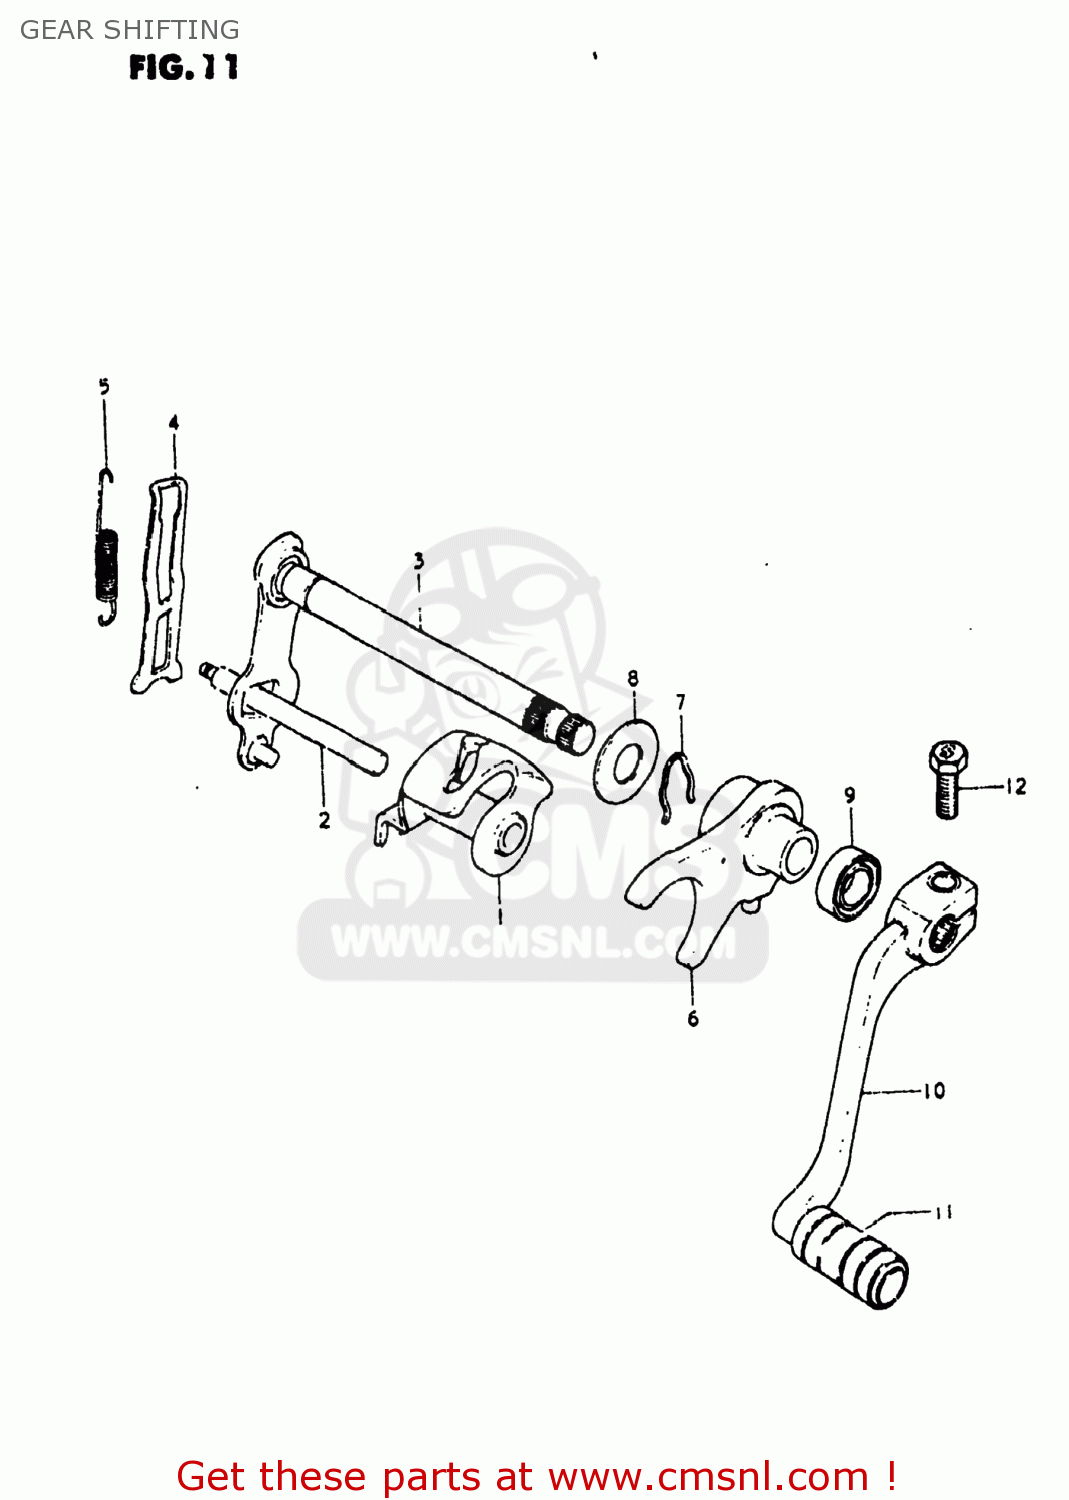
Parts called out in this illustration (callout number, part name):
1	CAM,GEAR SHIFT
2	SHAFT,GEAR SHIFT CAM
3	SHAFT,GEAR SHIFT
4	ARM,GEAR SHIFT CAM STOPPER
5	SPRING
6	FORK,GEAR SHIFT NO.1
7	SPRING,RETAINER
8	WASHER
9	OIL SEAL
10	LEVER ASSY,GEAR SHIFT
11	RUBBER,GEAR SHIFT PEDAL
12	RUBBER,GEAR SHIFT PEDAL
13	BOLT
